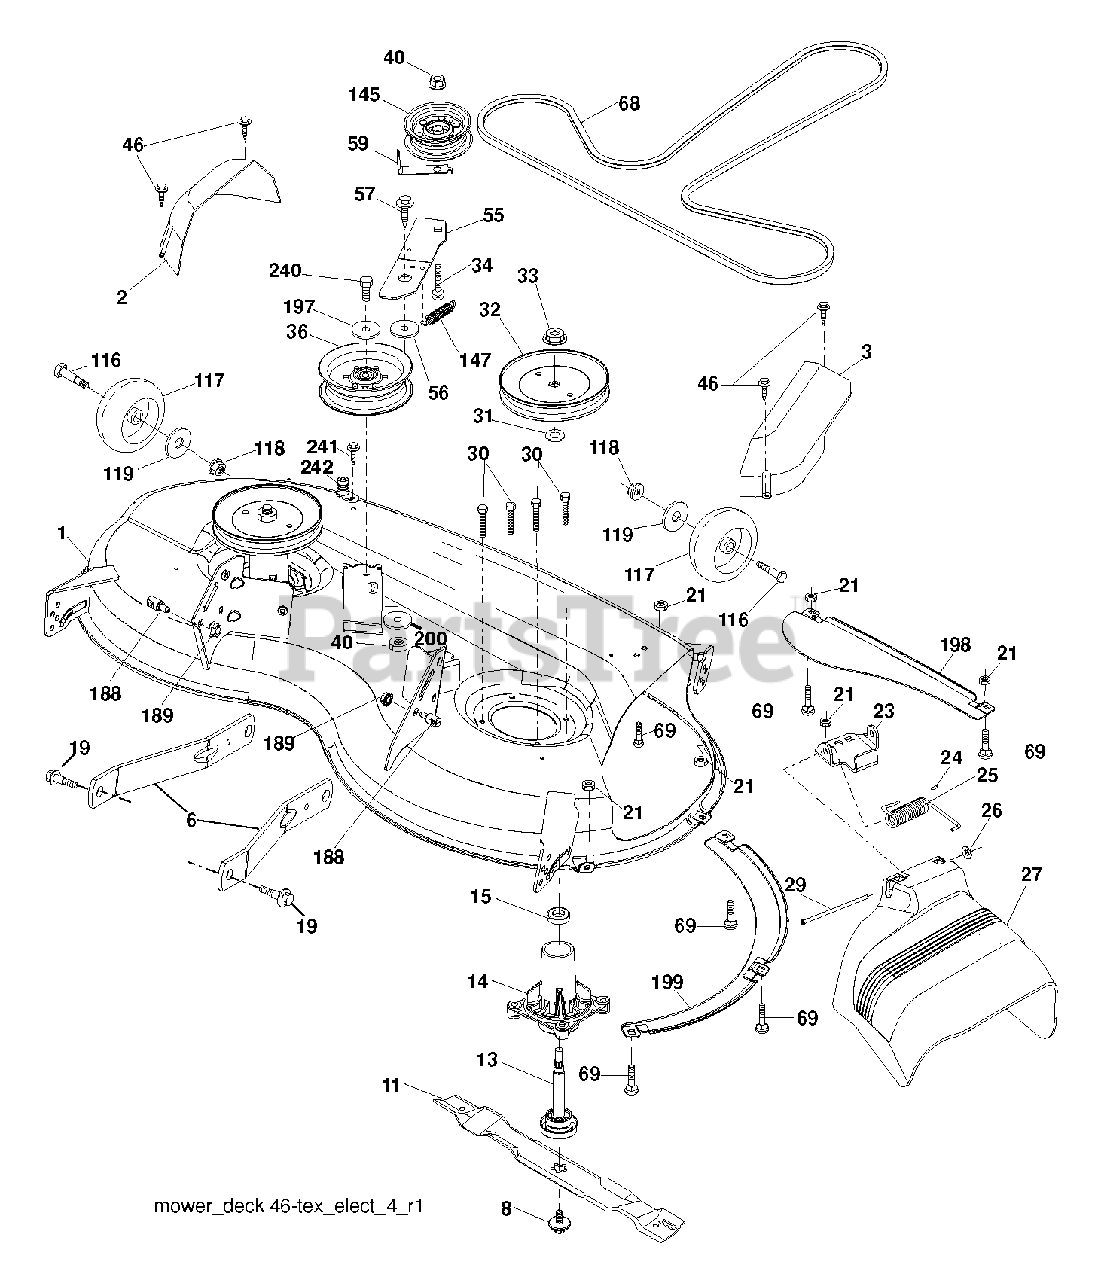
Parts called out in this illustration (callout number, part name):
1	DECK.WELDMENT.46"4GW.WHL.MS666
2	COVER MANDREL LH
3	COVER MANDREL RH
6	ARM.SUSPENSION.MOWER.R
8	BOLT.WASHER.ASM.7/16-2
11	BLADE 46" HI LIFT
13	SHAFT.ASM.MDRL.N/GREASE.38
14	HOUSING MANDREL
15	BEARING
19	BOLT.SHOULDER
23	BRKT.DEFLECTOR
24	CAP-SLEEVE LT
25	SPRING.TORSION.DEFLECT
26	NUT PUSH M
27	SHIELD, DEFLECTOR
29	HINGE ROD
30	SCREW, WASHER HEAD
33	NUT.FLANGE.LOCK.TOP
46	SCREW 1/4-20X5/8
55	IDLER.ARM
56	SPACER.RETAINER
57	SCREW 3/8-16X1
59	GUARD, BELT
68	V BELT
69	BOLT
117	WHEEL GAGE.HALF.SPOKED
147	SPRING.MOWER.DRIVE.ELECTRIC
188	STUD.FASTNER.W/ANTI-ROTATE
189	NUT LOCK HEX FLANGE 5/16-18
198	BAFFLE CENTER FRONT
199	BAFFLE FRONT RH
200	WASHER.13/32 X 1 X 1/2.11GUARD
240	BOLT-HEX EAK
242	PORT.WASHOUT
